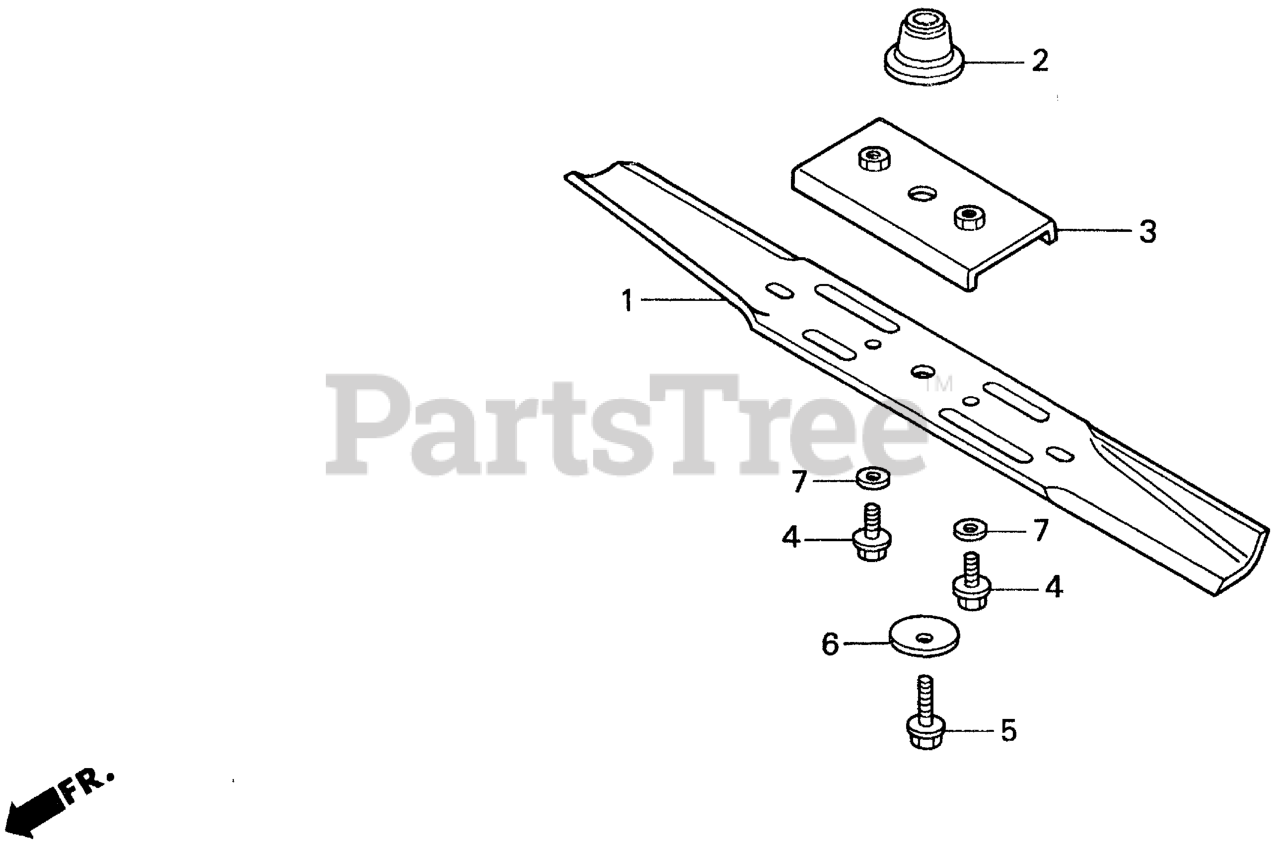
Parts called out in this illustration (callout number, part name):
1	BLADE, ROTARY
2	HOLDER, BLADE (A)
3	HOLDER, BLADE (B)
4	BOLT, FLANGE (12X25)
5	BOLT, BLADE HOLDER (10X28)
6	WASHER, BLADE
7	WASHER, SPRING (12MM)
